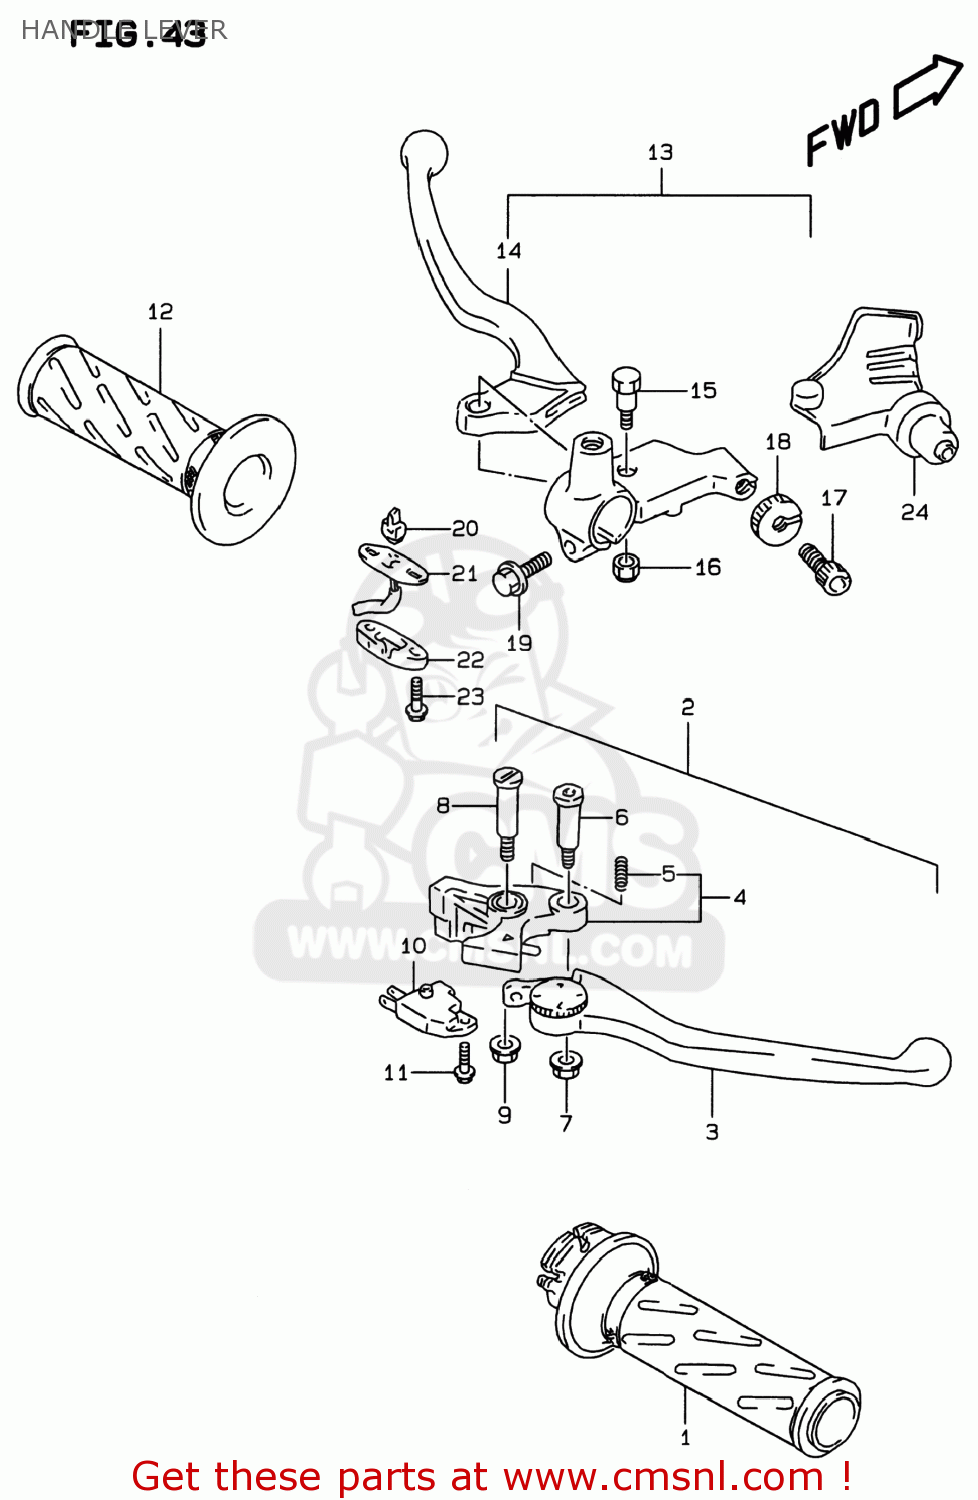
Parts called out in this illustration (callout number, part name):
1	GRIP,THROTTLE
2	LEVER ASSY,BRAKE
3	LEVER,ADJUST
4	KNOCKER
5	SPRING
6	BOLT,LEVER
7	NUT
8	BOLT,LEVER PIVOT
9	NUT
10	SWITCH ASSEMBLY,STOP
11	SCREW
12	GRIP,LEFT
13	LEVER ASSY,CLUTCH
14	LEVER,CLUTCH
15	BOLT,LEVER SET
16	NUT
17	ADJUSTER,CABLE
18	NUT,CABLE ADJUSTER
19	SCREW
20	CONTACT,SWITCH
21	HARNESS ASSY,WIRE
22	COVER,FR BK TERMINAL BASE
23	SCREW
24	COVER,CLUTCH LEVER
